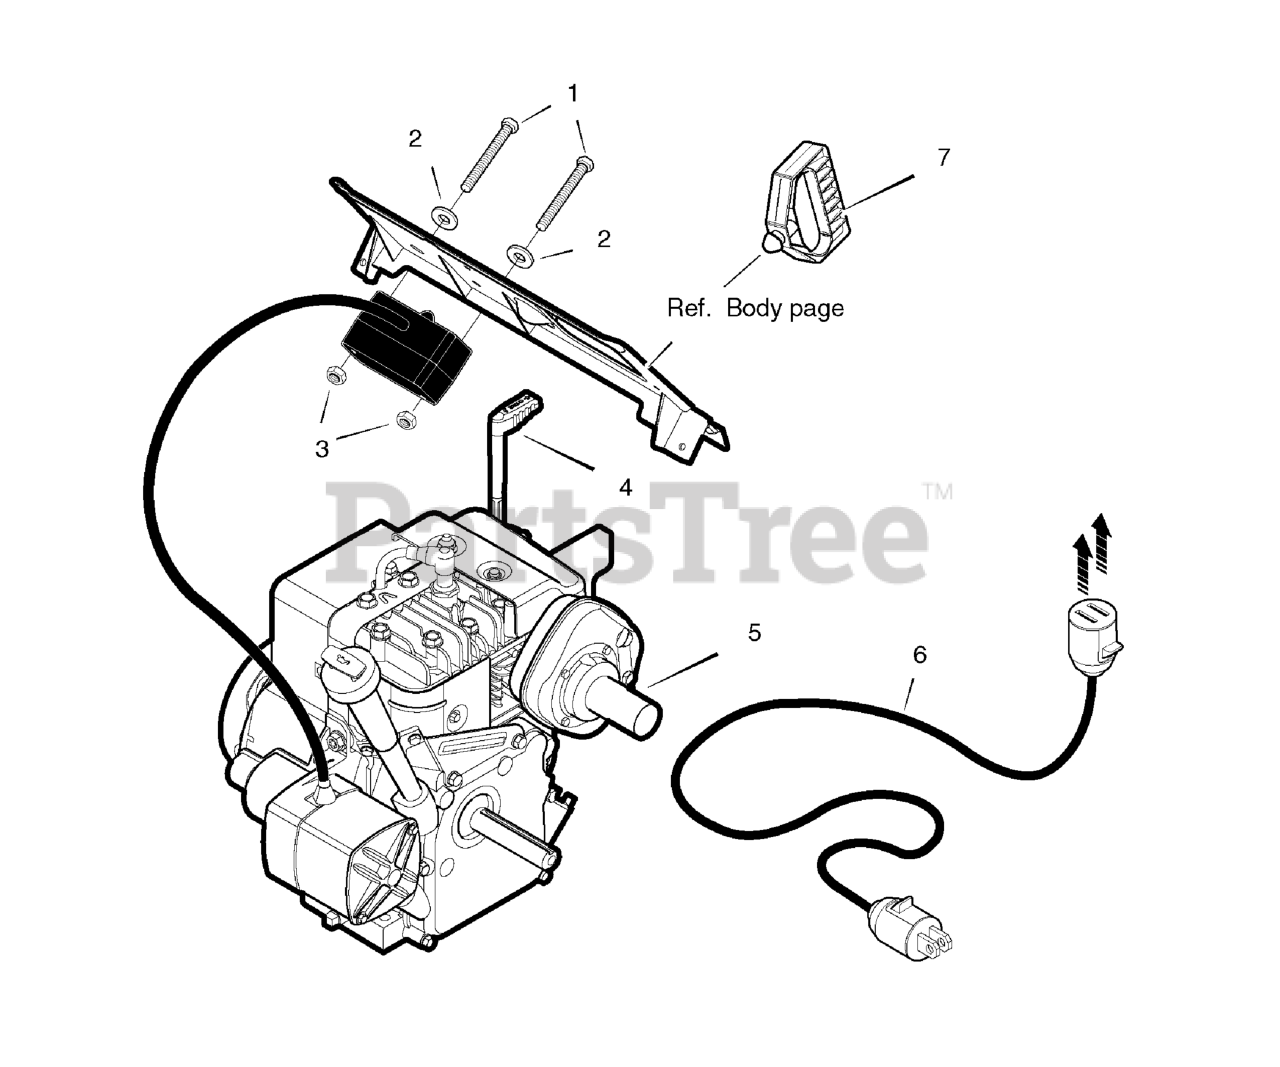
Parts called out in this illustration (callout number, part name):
1	SCREW, # 8 - 32 x 3
3	NUT, Keps
4	LEVER, Choke *
5-1	Muffler *
5-2	GASKET, Muffler *
5-3	SCREW, Torx, Socket-Head, Muffler *
5-4	WASHER, Split Lock
5-5	NUT, Hex, 5/16 - 18
5-6	BOLT, Hex, 5/16 - 18
6	CORD, Electric, 10FT. 110V
7	GRIP, Starter Rope
